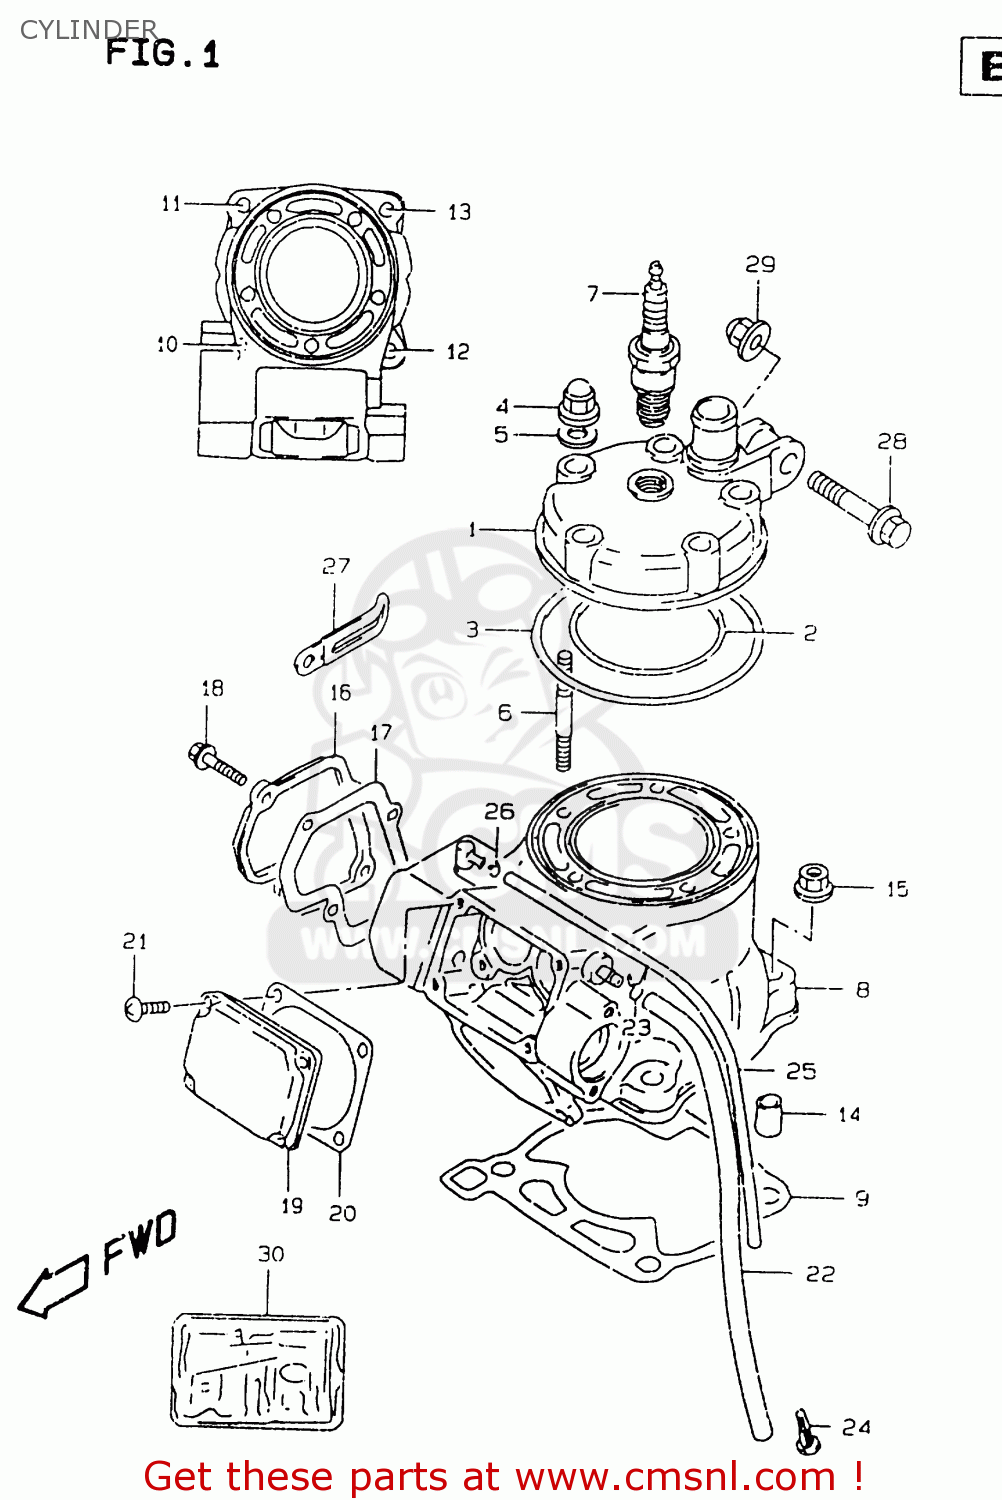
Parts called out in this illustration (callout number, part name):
1	HEAD,CYLINDER
2	O RING,CYLINDER HEAD NO.1
3	O RING,CYLINDER HEAD NO.2
4	NUT
5	GASKET(8.5X17X2.3) (NAS)
6	BOLT,STUD
7	PLUG,SPARK(R6918B-8)
8	CYLINDER
9	GASKET,CYLINDER (NAS)
10	STUD 8X25
11	BOLT,STUD
12	STUD BOLT
13	BOLT,STUD
14	PIN(8.4X11X14)
15	NUT
16	COVER,CYLINDER NO.1
17	GASKET,CYLINDER COVER NO.1 (NAS)
18	BOLT
19	COVER,CYLINDER NO.2
20	GASKET,CYLINDER COVER NO.2
21	BOLT
22	HOSE
23	CLIP
24	FILTER,EXH VALVE BREATHER HOSE
25	HOSE(5X8.2X600)
26	CLIP
27	CLAMP(L:45)
28	BOLT(8X41)
29	NUT
30	GASKET SET (NAS)
